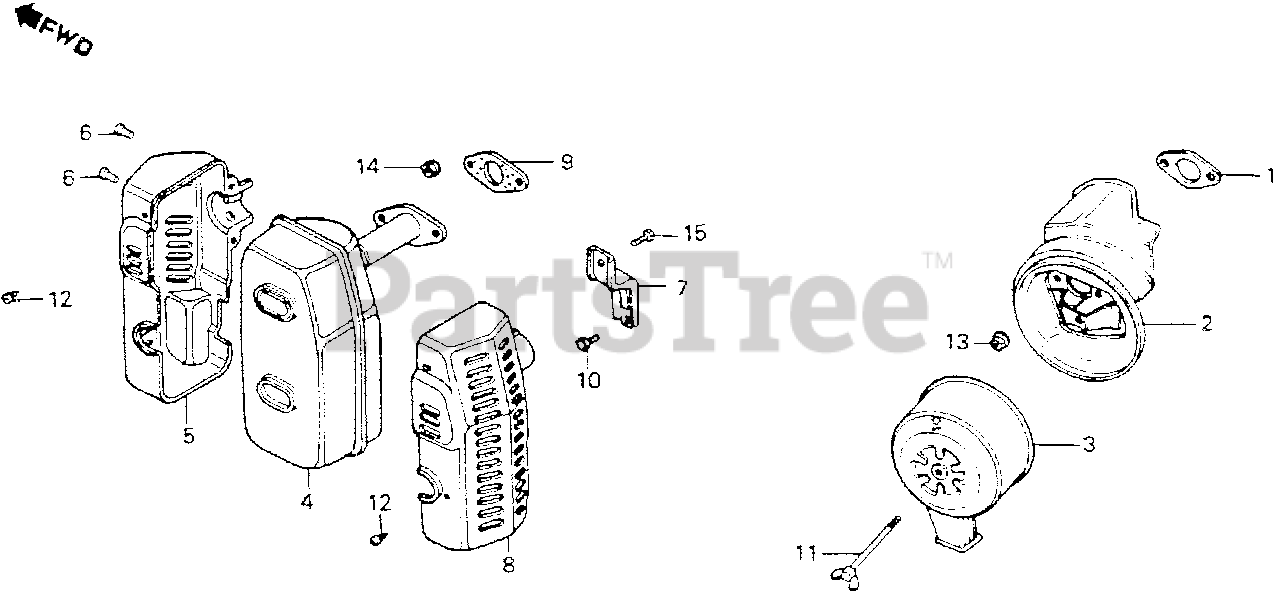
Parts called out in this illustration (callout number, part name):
1	GASKET, AIR CLEANER
2	HOUSING, AIR CLEANER (NOT AVAILABLE)
3	COVER, AIR CLEANER (NOT AVAILABLE)
5	PROTECTOR, L. MUFFLER
6	RIVET (4X5)
7	STAY, MUFFLER
8	PROTECTOR B, MUFFLER
9	GASKET, MUFFLER
10	BOLT, FLANGE (8X18) (NOT AVAILABLE)
11	BOLT, AIR CLEANER COVER
12	SCREW, TAPPING (4X8) (NOT AVAILABLE)
13	NUT, FLANGE (6MM)
14	NUT, FLANGE (8MM)
15	BOLT, FLANGE (6X10)
